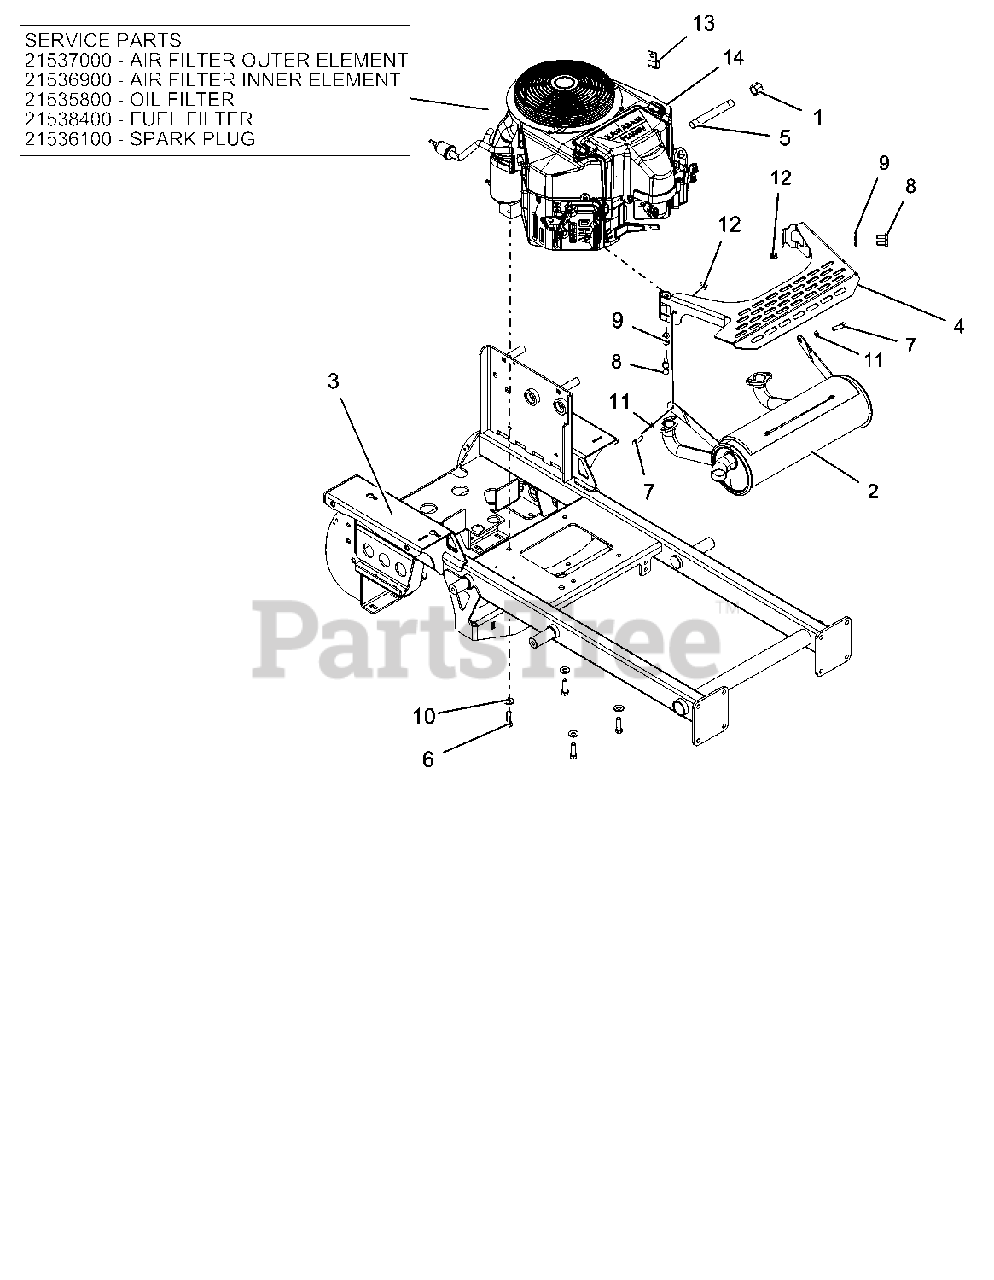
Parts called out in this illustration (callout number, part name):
1	PIPE CAP 3/8 NPT FEMALE
2	MUFFLER, KAW FS PROWALK
3	WLDMT, COMPACT PROSTANCE FRAME
4	SHIELD, MUFFLER
5	PIPE, .375" NPT X 5"
6	BLT-HEX.38-16X1.25 G5YZ NYTORQ
7	@BLT-HEX .31-18X1.00 GR5 YWZC
8	@BLT-HEX M8-1.25X20 YWZC
9	@WSHR-LK .31X.078 REG YWZC
10	WASHER, 3/8" SPRING DISC
11	@WSHR-FL-STL.281X.62X.065 YWZC
12	@NUT-LK-NYL-FLG .31-18 YWZC
14	FILTER,OIL - KAW
14	PLUG, SPARK
14	AIR FILTER, KAWASAKI FR
14	PRE FILTER, KAWASAKI FS
14	FUEL FILTER - KAWASAKI
14	ENG. KAW FS600
